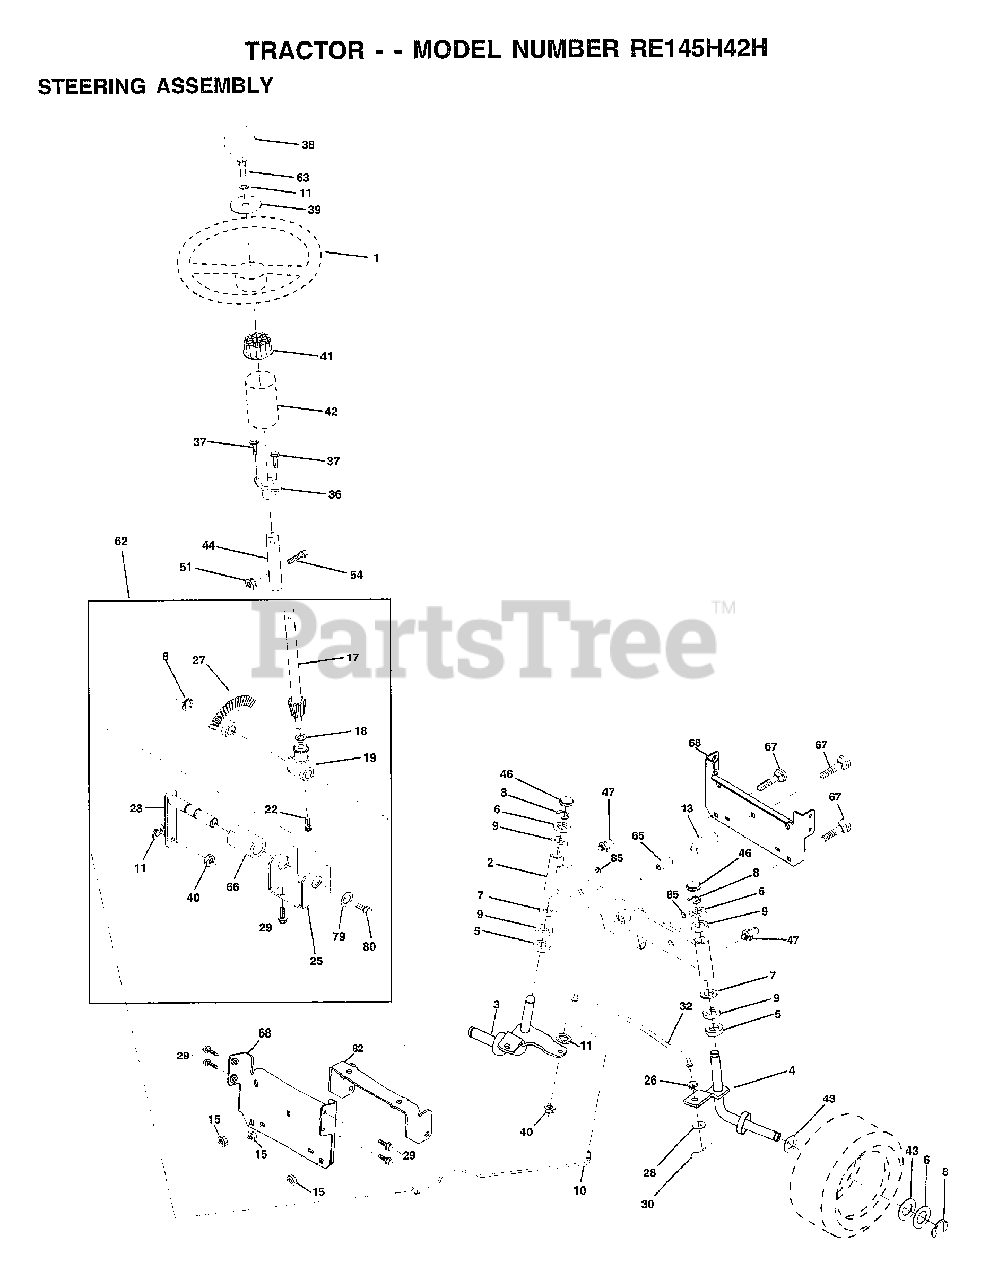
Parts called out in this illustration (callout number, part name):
2	AXLE ASM
3	SPINDLE ASM
4	SPINDLE ASM
5	WASHER .T
6	WASHER
7	WASHER
8	RING
9	COL. SRTG. BEAR.
10	LINK DRAG
11	LOCKWASHER
13	SPACER BEARING
15	NUT.HXFLG.LOCK.
17	SHAFT ASM STEERIN
18	THRUST WASHER
19	SUPPORT.SHAFT.STEER
22	SCREW.HX.WSH.HD
23	SHAFT.ASM.PITMAN
25	BRKT-STEERING
26	BUSHING.DRAGLINK
27	GEAR SECTOR
28	WASHER
29	SCREW
30	COTTER PIN
32	TIE ROD
36	BUSHING.STEERING
37	"SCREW-TT,10-32 FL"
38	ST WHL INSERT CAP
39	WASHER
40	GRIPCO NUT
41	ADAPTER LT
42	BOOT.STEERING.DASH.P/L
43	WASHER
44	EXT SHAFT STEERIN
46	CAP
47	ZERK M
51	NUT
54	BOLT
62	KIT.STEER.ASM
63	BOLT
65	"SPACER BRCAE,AXLE"
66	"BEARING-ARM,PITMA"
67	BOLT RDHD 3/8-16
68	BRACE AXLE
79	WASHER
80	BOLT.HX.NYLON3/8-16X3/
82	BRKT SUSP CHASSIS FRT
85	XMAS TREE FASTNER
